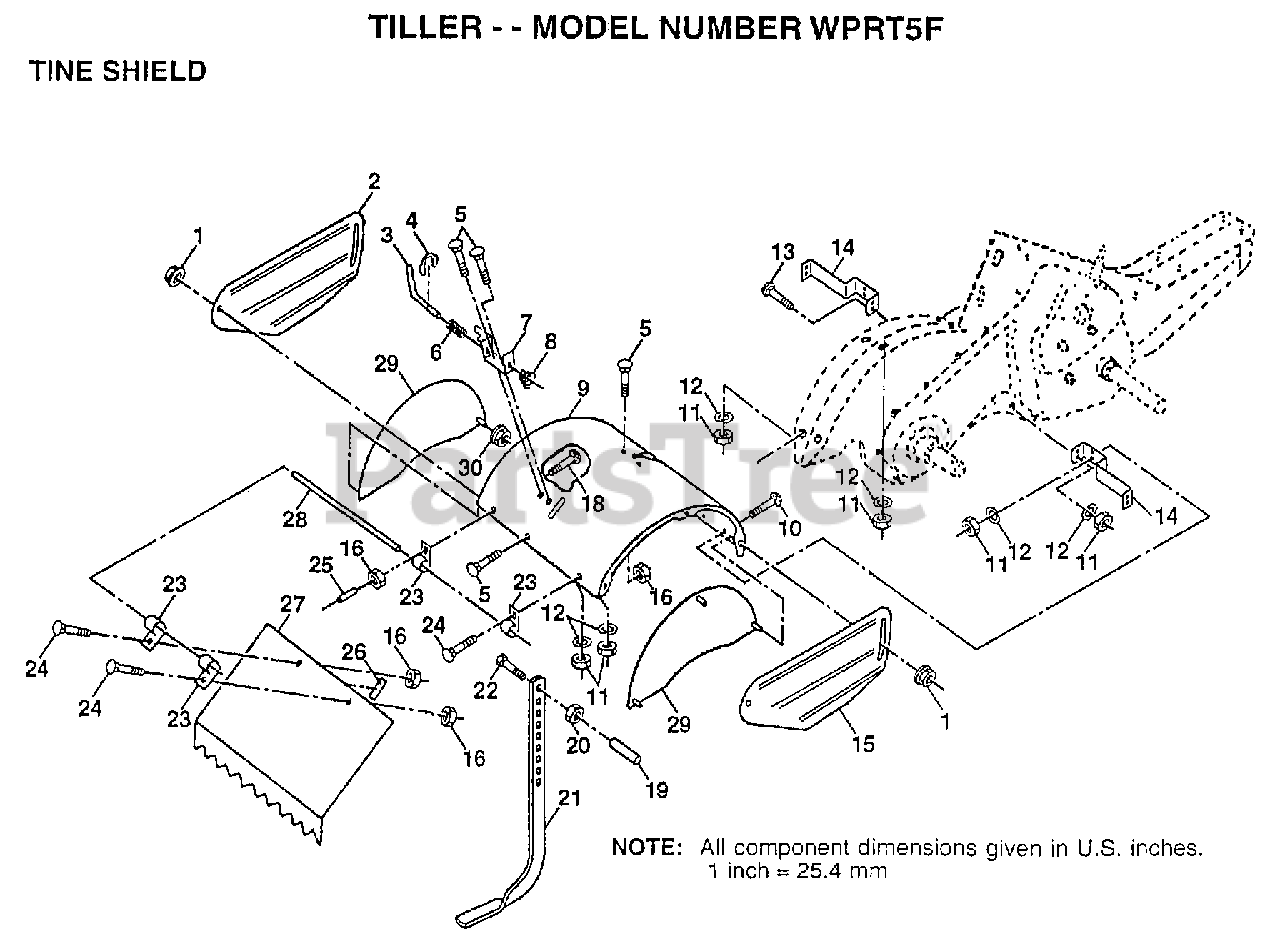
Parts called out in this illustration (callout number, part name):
1	NUT
2	SHIELD.SD.OUT.LH
3	STAKE PIN TI
4	KLIP RING TI
5	BOLT
6	SPRING TI
7	LATCH BRACKET TI
8	SPRING CRT
9	TINE SHIELD
10	BOLT
11	NUT.HEX.5/16-18
12	LOCKWASHER
13	BOLT
14	"BRACKET,SHIELD"
15	SHIELD.SD.OUT.RH
16	NUT
18	BOLT
19	GRIP CRT
20	NUT.HEX.3/8-16UNC
22	BOLT
23	HINGE CRT
24	BOLT
25	VINYL CAP TI
26	PAD IDLER TI
27	LEVELING SHIELD
28	PIN HINGE
29	SIDE SHIELD
30	LOCKNUT TI
